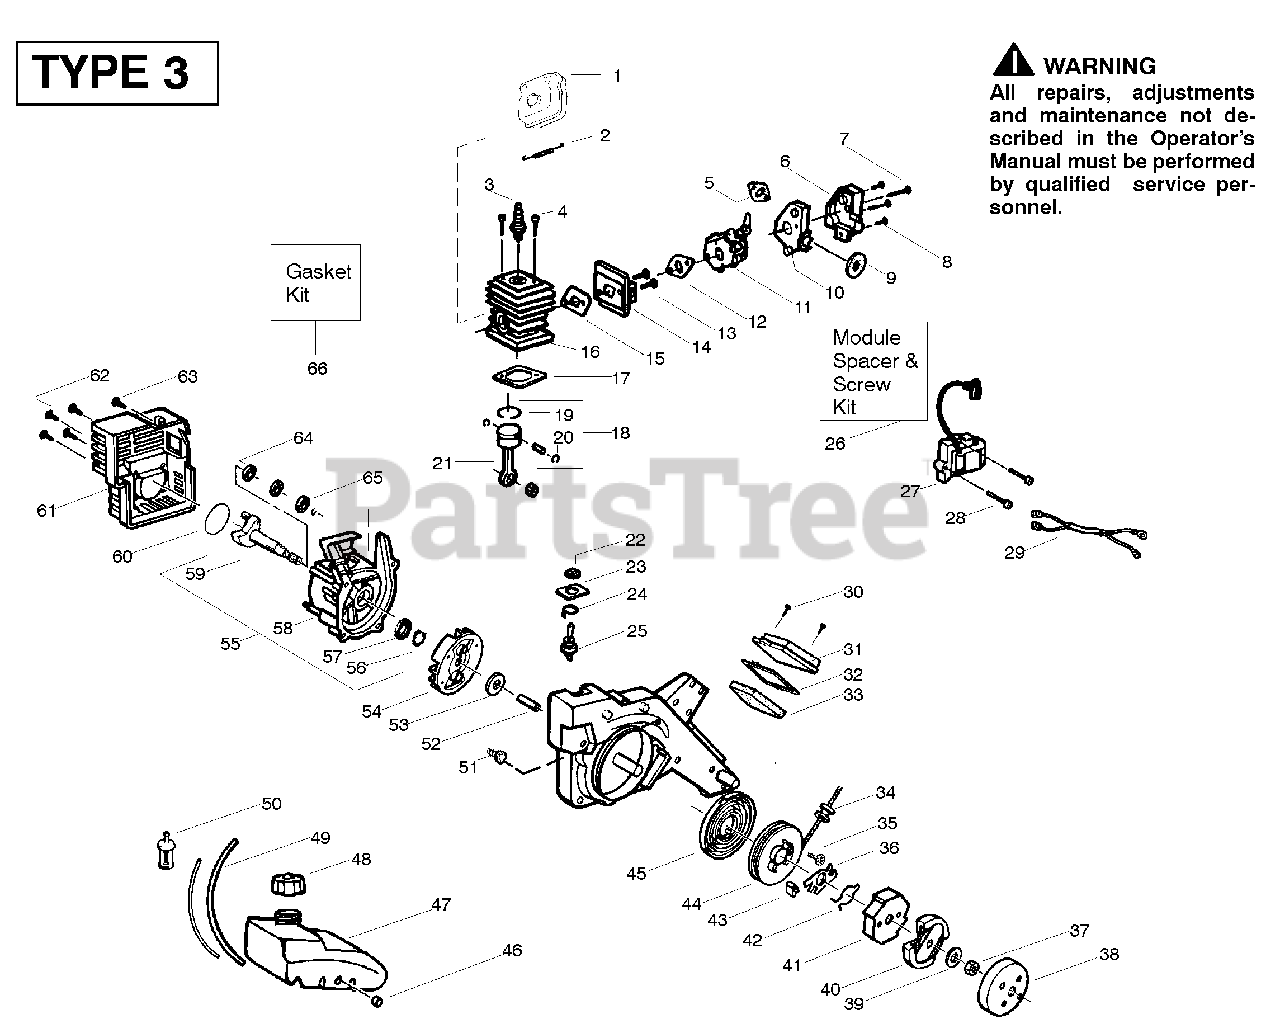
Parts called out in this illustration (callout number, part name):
1	Kit-Muffler
2	Spring-Muffler
3	Plug-Spark (RCJ-6Y)
5	Gasket-Carb/Bracket(kit)
6	Cover-Air Box
9	Seal-Foam (kit)
10	Base-Air Box
11	Kit-Carb. (Wt-630)
12	Gasket-Carb.(kit)
14	Adapter-Carb.
15	Gasket-Cyl./Carb. (kit)
16	Cylinder
17	Gasket-Cyl. (kit)
18	Kit-Piston
19	Ring-Piston
20	Retainer-Pin
21	Kit-Conn. Rod Assy.
22	Boot-Switch w/nut
23	Plate-Switch Indicator
24	Terminal-Grounding
25	Assy-Gound Switch
26	Kit-Mod. spacer/screw
27	Module-Ignition
29	Assy-Switch Wire
31	Cover-Air Filter
32	Gasket-Cover (kit)
33	Foam-Air Filter
36	Cam-Starter
38	Drum-Clutch
39	Washer-Flywheel
40	Assy-Clutch
41	Cup-Starter
42	Wire-Starter Dog
43	Dog-Starter
44	Kit-Starter Pulley
45	Spring-Starter
46	Isolator-Crankcase
47	Assy-Fuel Tank
48	Assy-Fuel Cap
49	Kit-Fuel Line
50	Assy-Fuel Pick-up
51	Clip-Pine Tree
52	Spacer-Flywheel
53	Washer-Flat
54	Assy-Flywheel
55	Assy-C/shaft & C/case
56	Retainer-C'shaft
57	Kit-Crankcase Seal
58	Assy-C'case
59	Assy-Crankshaft
60	O-ring-c'case/shrd (kit)
64	Bearing-Inner
65	Bearing-Outer
66	Kit Gasket
